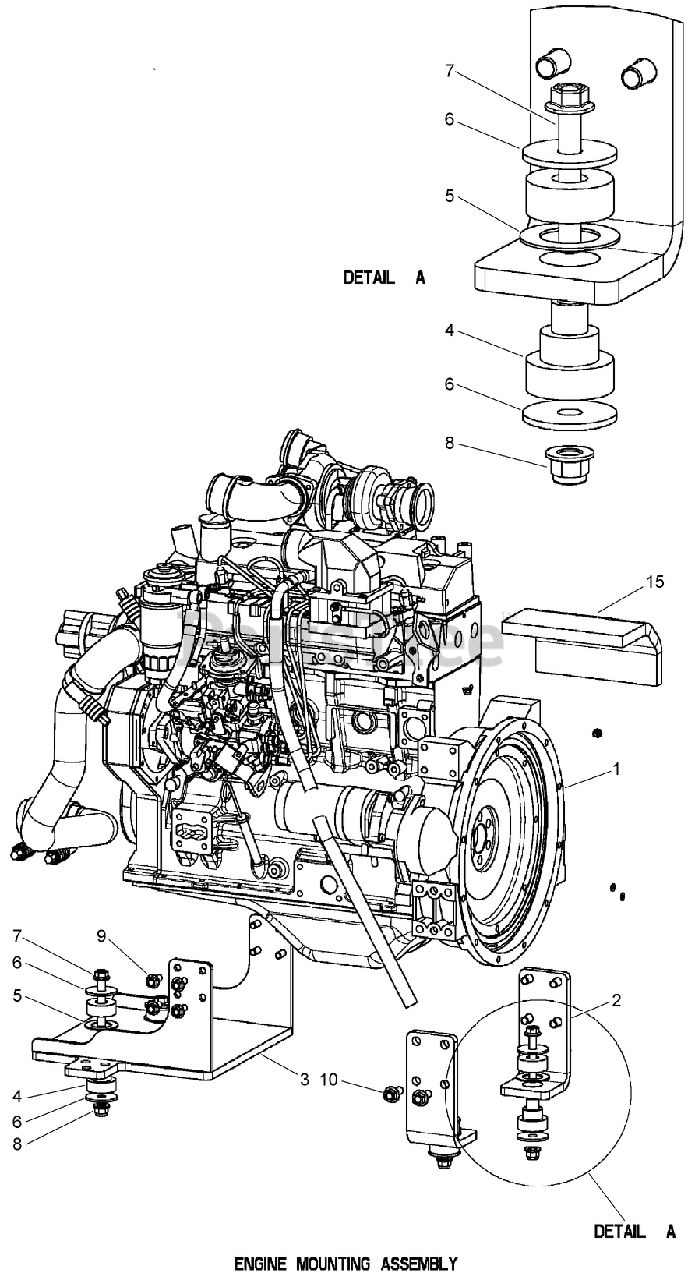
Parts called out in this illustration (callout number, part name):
1	ENGINE ASM
2	MOUNT - Engine, Rear
3	ASSEMBLY - Engine/Radiator Mount
4	ISOLATOR-MOUNTING, UNIVERSAL
5	SPACER-ISOLATOR
6	WASHER-FLAT
7	SCREW-HHF
8	NUT-HHF, LOCK
9	SCREW-FLANGE
10	SCREW, METRIC FLANGE w/BODY-M12 x 30
15	SHIELD-HEAT
